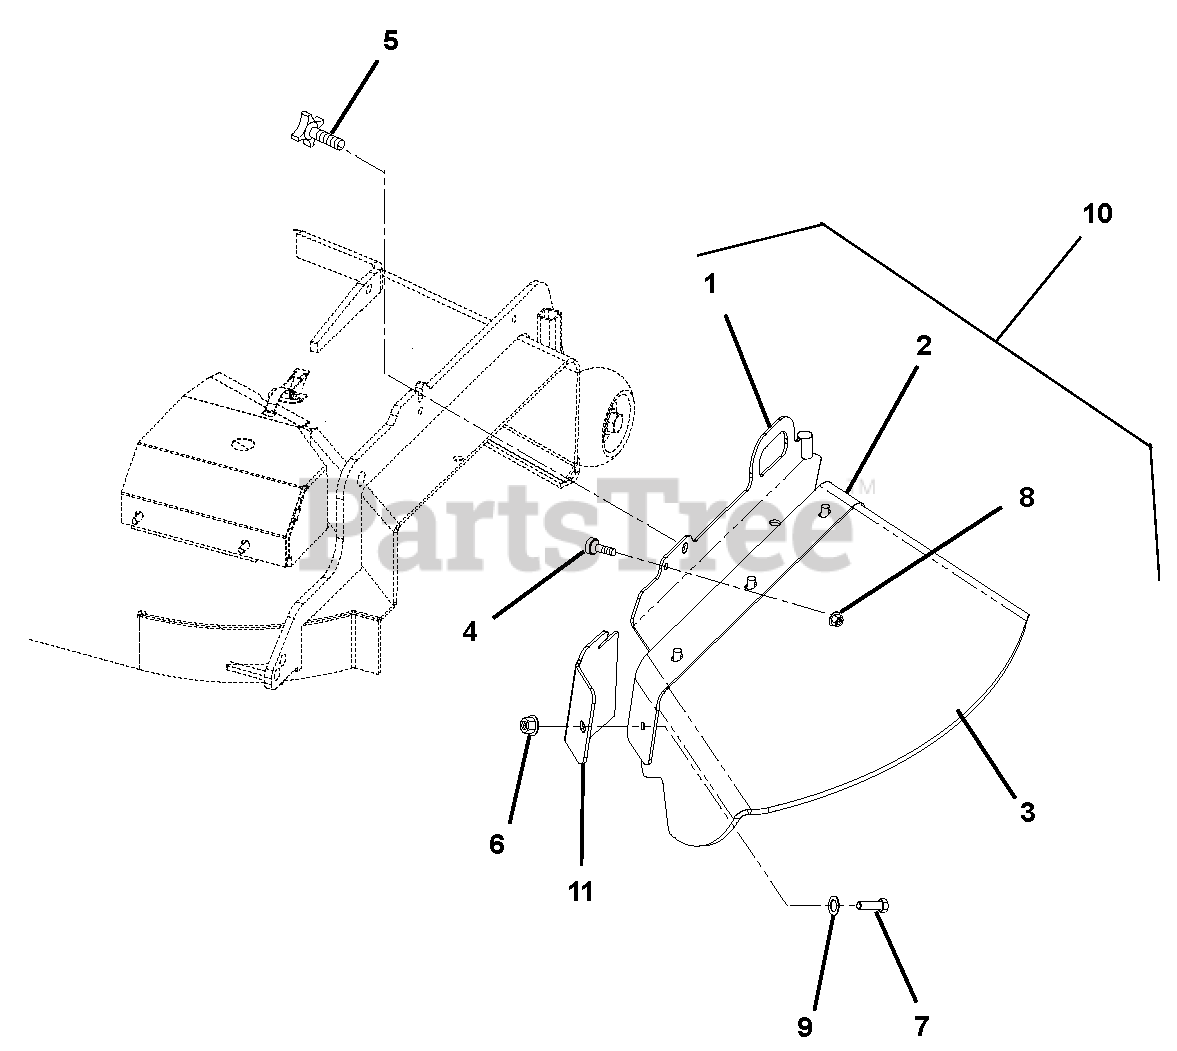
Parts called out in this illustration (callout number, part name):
1	Weldment, Discharge Chute Mount
2	Plate, Discharge Shield Support
3	Shield, Rubber Discharge
4	Bumper, Rubber
5	Knob, 3/8 x 1.25 - 4 Prong
6	Locknut, 3/8-16 Whiz
7	Bolt, 3/8-16 x 1 CRG 5
8	Locknut, 5/16-18 Whiz
9	Washer, .500 Reg, Flat
10	Assembly, Discharge - Rubber *(contains items 1 throug
11	Cover, 54" Discharge (992220)
